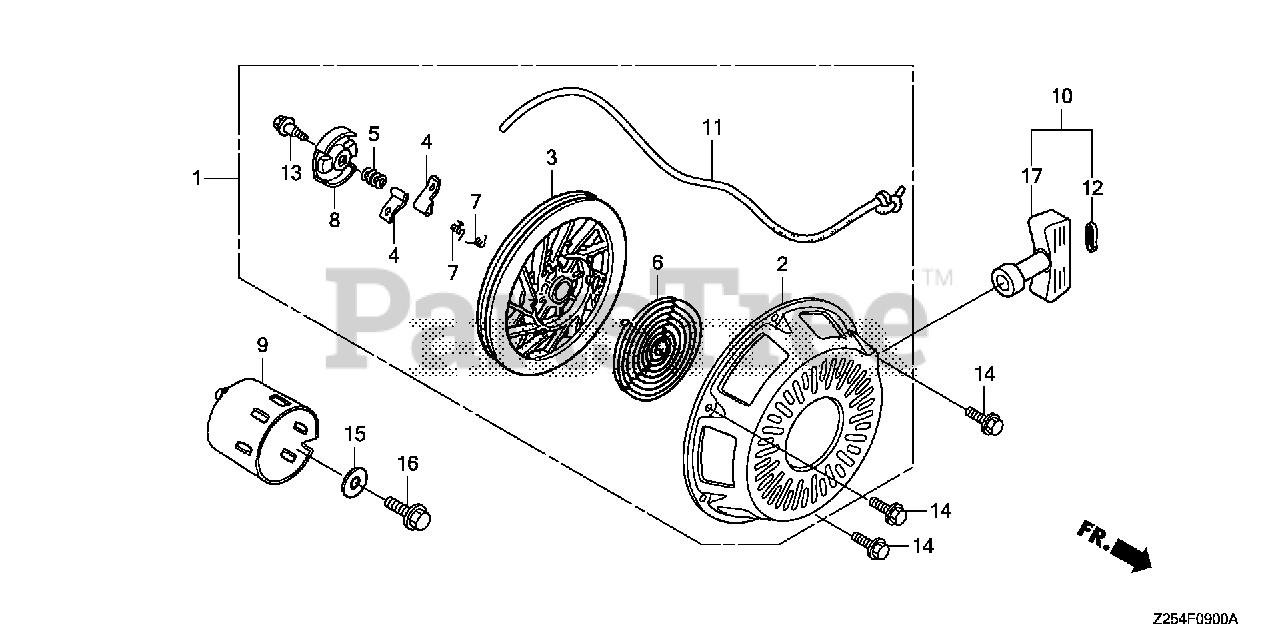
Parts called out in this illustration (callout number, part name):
1	STARTER ASSY., RECOIL
2	CASE, RECOIL STARTER
3	PULLEY, RECOIL STARTER
4	RATCHET, STARTER
5	SPRING, FRICTION
6	SPRING, STARTER RETURN
7	SPRING, RATCHET
8	RETAINER, SPRING
9	PULLEY, STARTER
10	GRIP, STARTER (FOR U.S.A.)
11	ROPE, RECOIL STARTER
12	REINFORCEMENT, GRIP
13	SCREW, CENTER
14	BOLT, FLANGE (6X12) (CT200)
15	WASHER (10MM)
16	BOLT, FLANGE (10X25)
17	GRIP, STARTER (FOR U.S.A.)
17	GRIP, STARTER
